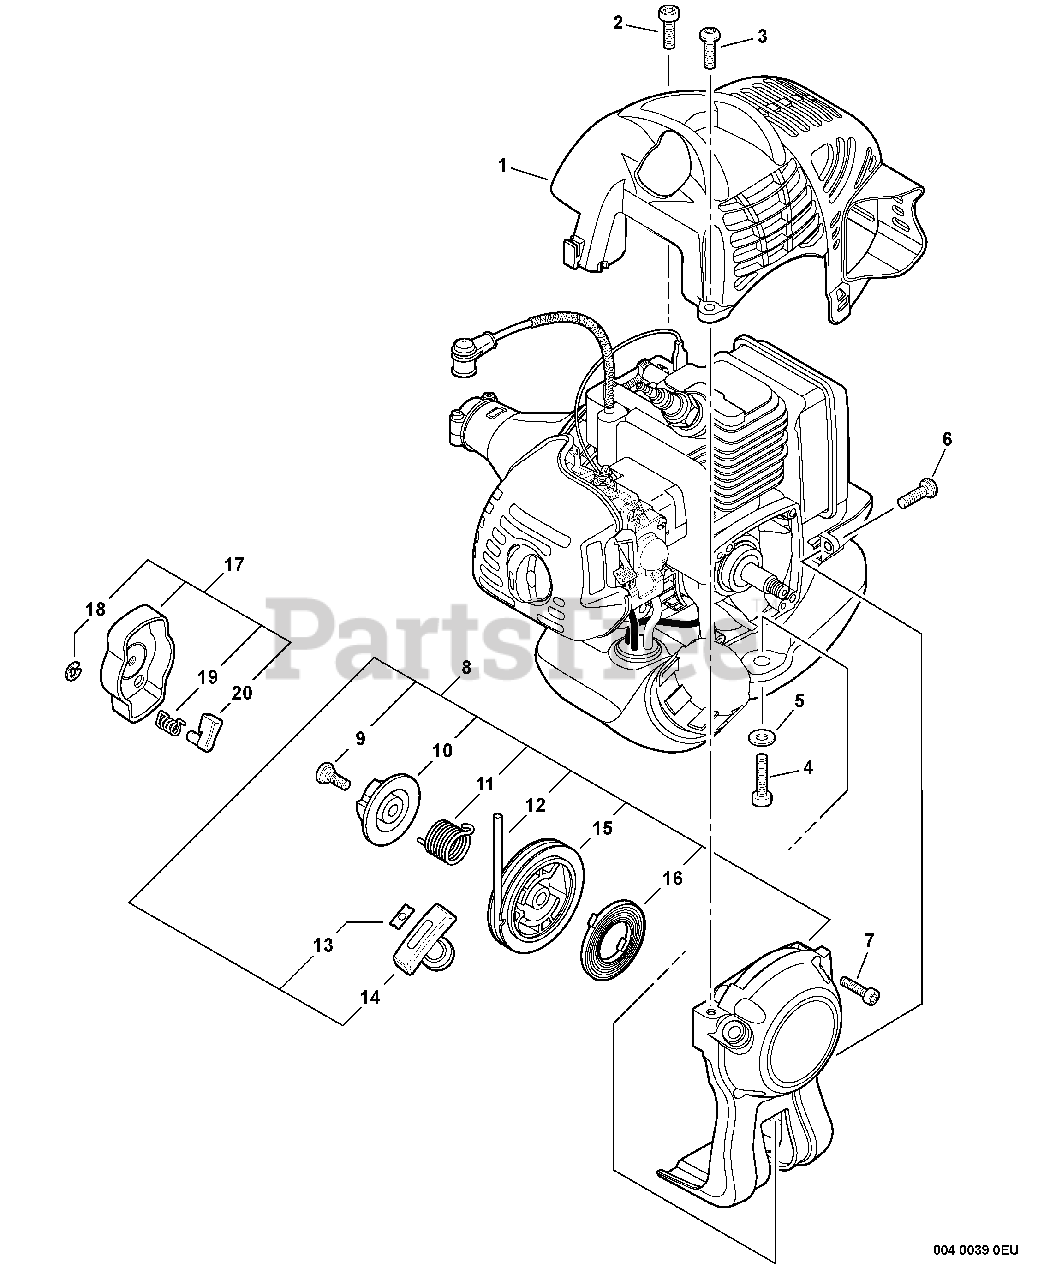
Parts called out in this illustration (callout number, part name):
1	COVER, ENGINE
2	BOLT, TORX 5×16
3	BOLT, TORX 5×16
4	BOLT, TORX 5×20
5	WASHER 5.5×12×0.8
6	BOLT, TORX 5×16
7	BOLT, TORX 4×16
8	STARTER ASSY, RECOIL
9	SCREW
10	PLATE, CAM (NLA SEE PB 15-06)
11	SPRING, TORSION
12	ROPE, STARTER
13	RETAINER, ROPE
14	GRIP, STARTER
15	REEL, ROPE
16	SPRING, RECOIL
17	PAWL ASSY, STARTER
18	E-RING 4
19	SPRING, RETURN
20	PAWL, STARTER
